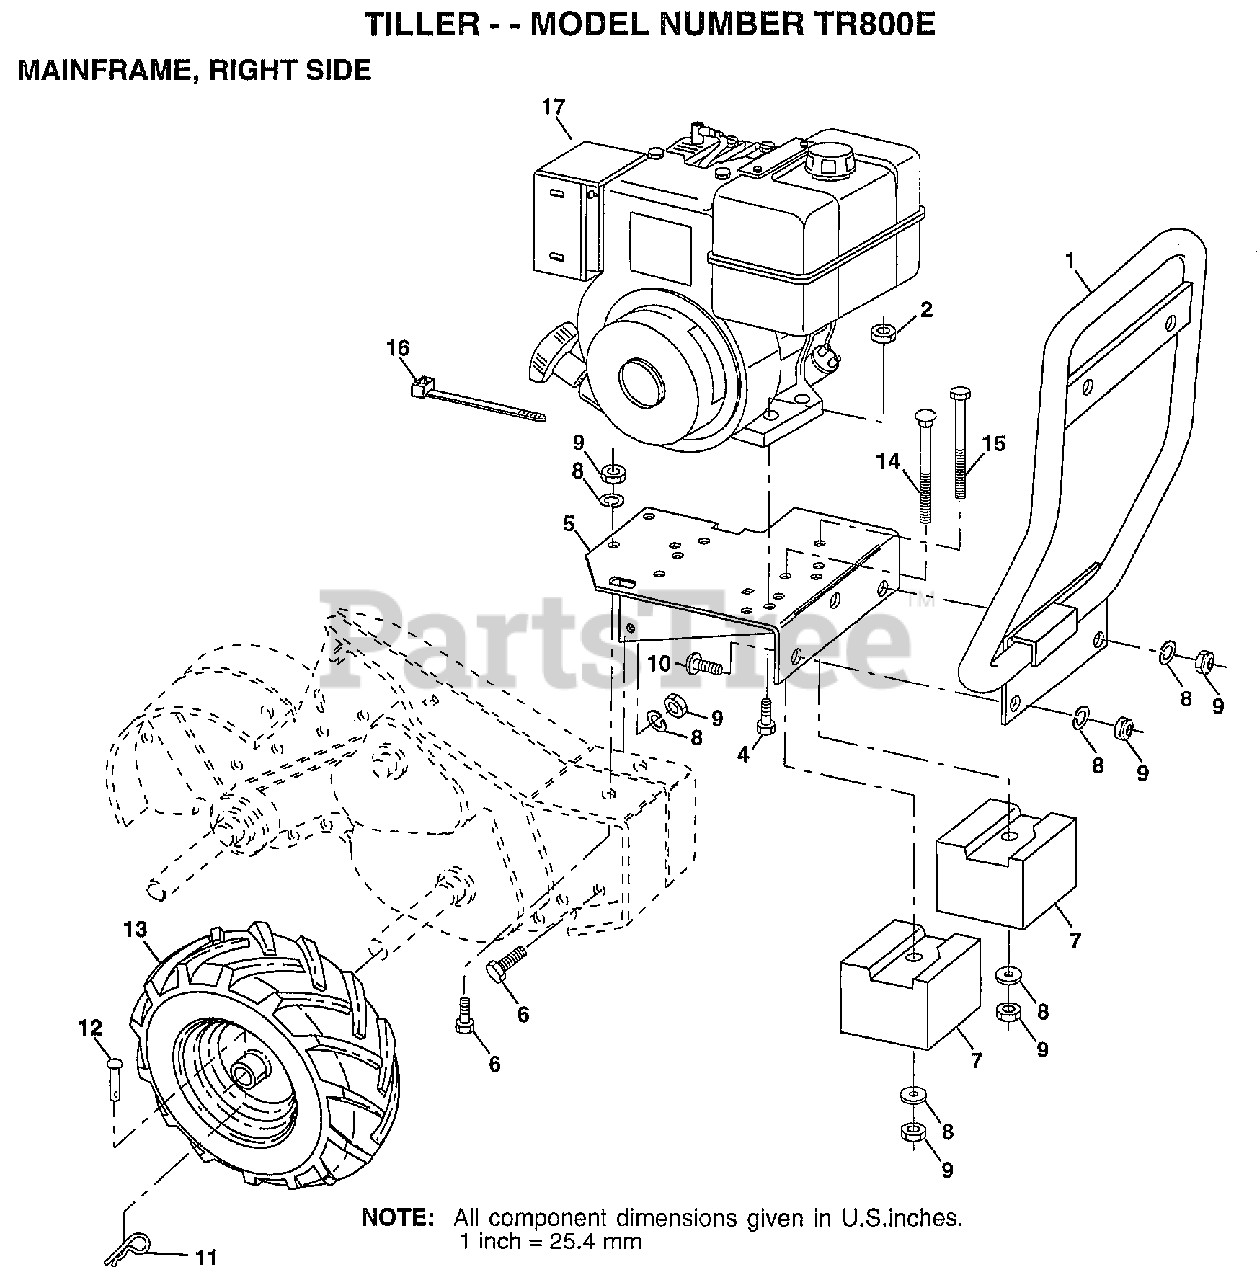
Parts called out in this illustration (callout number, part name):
1	BUMPER.ASM
4	BOLT
5	"ASM. ENGINE, BASE"
6	BOLT
7	COUNTERWEIGHT CRT
8	LOCKWASHER
9	NUT.HEX.3/8-16UNC
12	RIVET.PAN HD.1.75
13	TIRE TI
13	RIM.16X4X8.WHT
15	BOLT.3/8-16X4.5
16	TIE CABLE CRT
17	BOLT CRT
